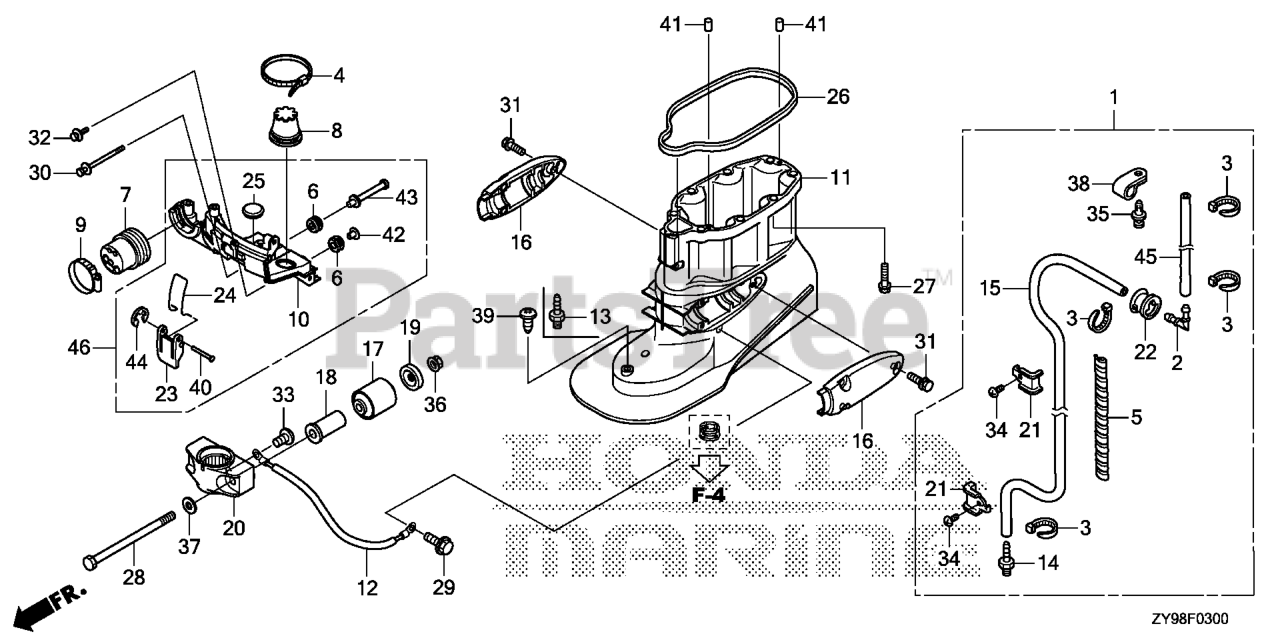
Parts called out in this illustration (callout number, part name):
1	TUBE KIT, SPEED SENSOR
2	JOINT A, BREATHER
3	BAND, WIRE
4	BAND (BLACK 3.5X140)
5	TUBE, SPIRAL
6	GROMMET, CASE (LOWER)
7	GROMMET, REMOTE CONTROL CABLE
8	GROMMET, CASE (LOWER) (C)
9	BAND, CASE GROMMET (LOWER)
10	BRACKET, FR. COVER (LOWER) *NHB14M* (AQUA MARINE SILVER METALLIC)
11	CASE, EXTENSION *NHB14M* (AQUA MARINE SILVER METALLIC)
12	WIRE, LEAD (1.5X137MM)
13	NIPPLE, SENSOR
14	NIPPLE, SENSOR
15	TUBE, SPEED SENSOR
16	HOUSING, MOUNTING (LOWER) *NHB14M* (AQUA MARINE SILVER METALLIC)
17	MOUNT, RUBBER (LOWER)
18	COLLAR, MOUNTING (LOWER)
19	STOPPER, MOUNT (LOWER)
20	HOUSING, CENTER MOUNTING (LOWER) *NHB14M* (AQUA MARINE SILVER METALLIC)
21	PLATE, SPEED SENSOR TUBE
22	BUSH, MOTOR CODE
23	LEVER, FASTENER
24	WIRE, FASTENER
25	CAP, L. SIDE COVER
26	SEAL B, COVER (LOWER)
27	BOLT, FLANGE (10X40)
28	BOLT, HEX. (12X186)
29	BOLT, FLANGE (6X12)
30	BOLT-WASHER (6X95)
31	BOLT-WASHER (8X30)
32	BOLT-WASHER (6X27)
33	SCREW, PAN (6X8)
34	SCREW, PAN (6X8)
35	SCREW, RIVET (5X10)
36	NUT, FLANGE (12MM)
37	WASHER, PLAIN (12MM)
38	CLIP (14MM)
39	CLIP (7MM)
40	PIN (5X44.5)
41	PIN, DOWEL (6X10)
42	COLLAR, MODULE IGNITION CONTROL CASE (CDI)
42	COLR, CDI UNIT CASE
42	COLLAR (12X6.5)
43	COLLAR, FR. BRACKET
44	E-RING (4MM)
45	BULK HOSE, VACUUM (5X3000) (5X250)
46	BRACKET *NHB14M*
